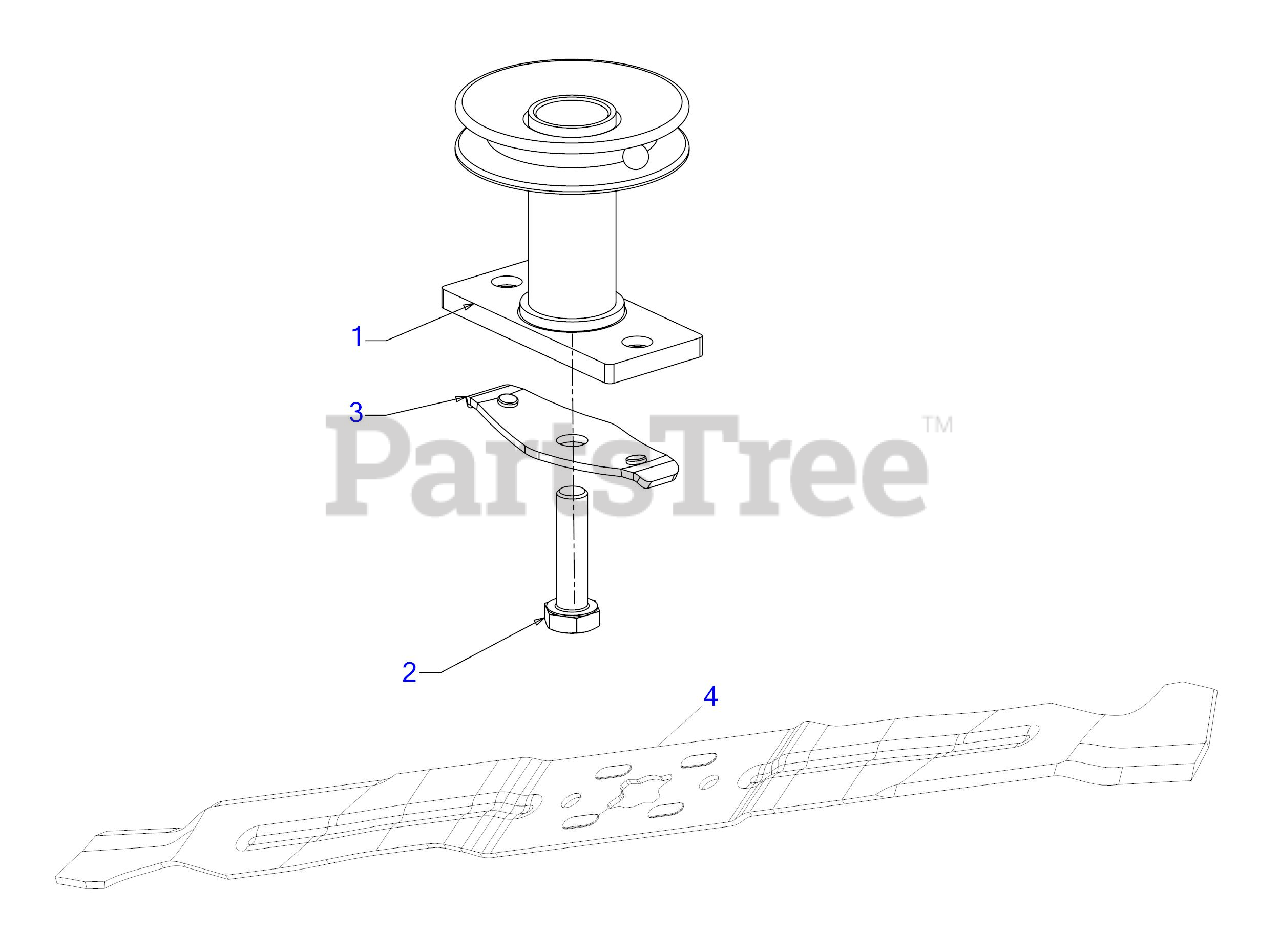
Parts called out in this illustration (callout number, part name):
1	ADAPTER ASSEMBLY
2	SCREW 3/8-24 x 1.50 GR8
3	BLADE BELL SUPPORT
4	21" MULCHING BLADE (2-IN-1)
